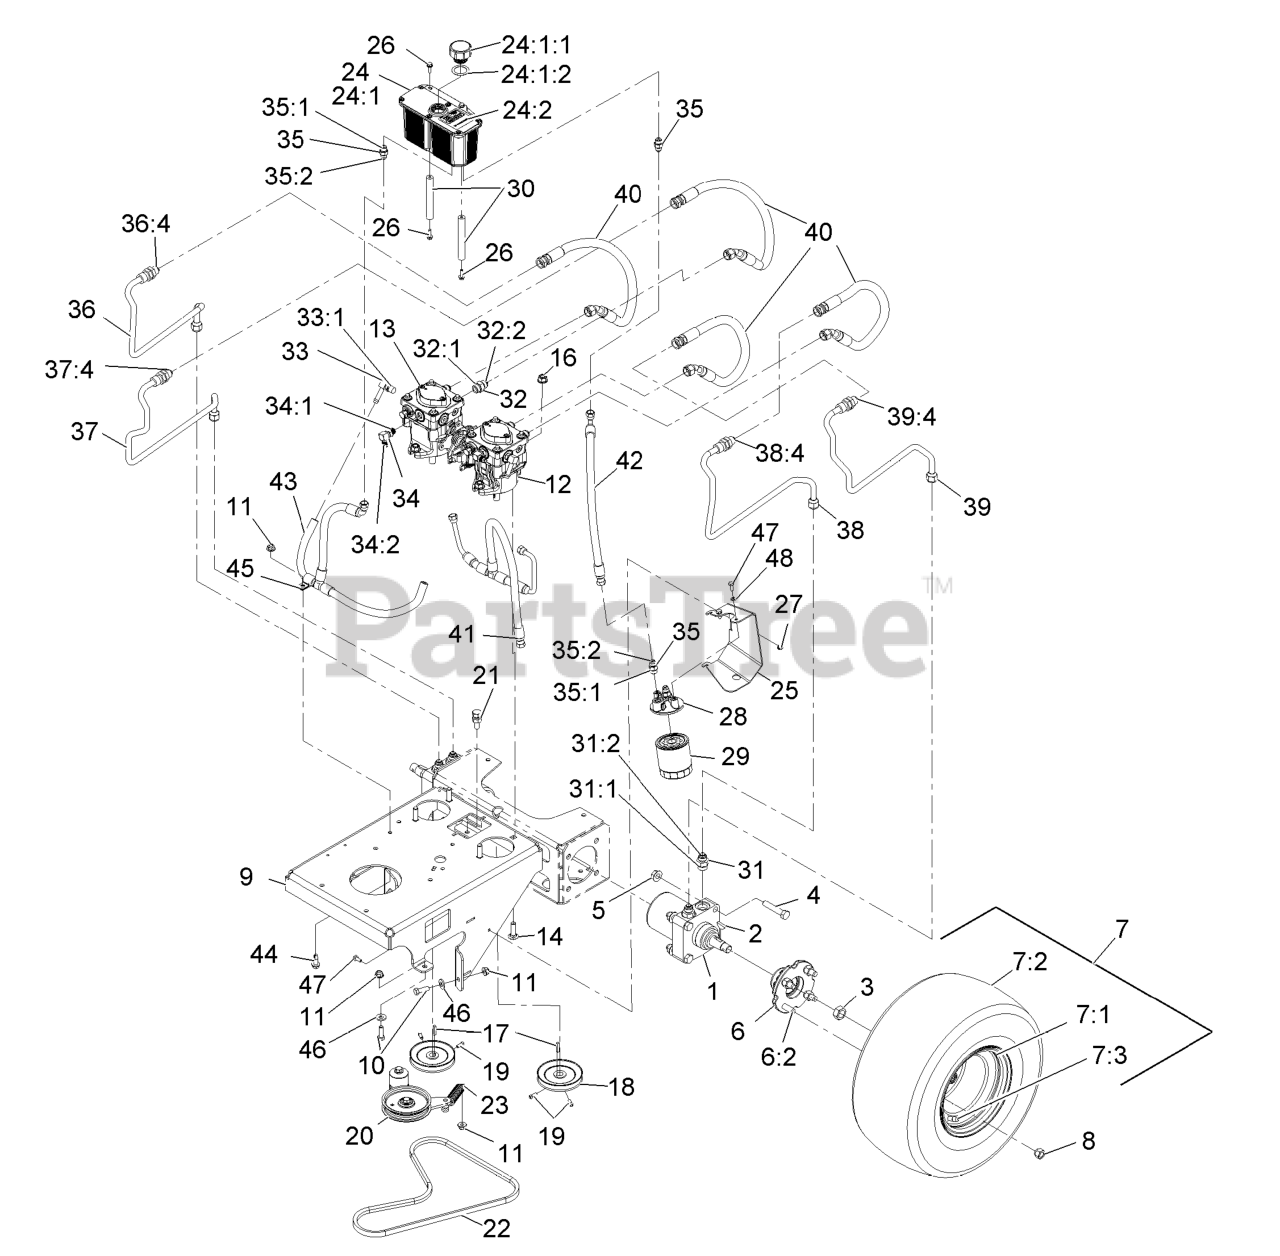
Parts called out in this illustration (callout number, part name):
1	HYD MOTOR ASM
2	KEY-WOODRUFF
3	NUT-MOTOR, WHEEL
4	SCREW-HH
6	WHEEL HUB ASM
6:2	STUD-TYPE, DRIVE
7	WHEEL/TIRE ASM
7:1	RIM-8 INCH
7:3	Stem-Valve
8	NUT-LUG
9	ENGINE BASE
10	SCREW-HH
11	NUT-HF, NI
12	PUMP - HYDRAULIC
13	PUMP-HYDRAULIC
14	SCREW-HH
16	NUT-HF, NI
18	PULLEY-PUMP
19	SCREW-SET
20	Pump Idler Asm
22	BELT-V
23	SPRING-EXTENSION
24	RESERVOIR ASM
24:1	Reservoir-Hyd
24:1:1	Cap-Reservoir, HYD
24:1:2	GASKET-CAP
24:2	DECAL-HYDRAULIC TANK
25	PLATE-FILTER MOUNT
26	SCREW-HHF
28	HEAD-FILTER
29	FILTER-25 MICRON, BI-DIRE
30	ROD-RESERVOIR STAND
31	FITTING-STRAIGHT
31:1	O-RING
32	FITTING-STRAIGHT
33	FITTING-ELBOW, 90
33:1	O-RING
34	FITTING-90 DEG
35	FITTING-STRAIGHT
36	HYDRAULIC TUBE ASM
36:4	FACE SEAL O-RING #8
37	HYDRAULIC TUBE ASM
37:4	FACE SEAL O-RING #8
38	HYDRAULIC TUBE ASM LH
38:4	FACE SEAL O-RING #8
39	HYDRAULIC TUBE ASM LH
39:4	FACE SEAL O-RING #8
40	HOSE ASM-HYD HP 1/2
42	HOSE ASM-HYD LP 3/8X14.4
44	SCREW-TAPPING
45	CLIP-LOOM
46	WASHER-BELLEVILLE
47	SCREW-HH
48	WASHER-LOCK
